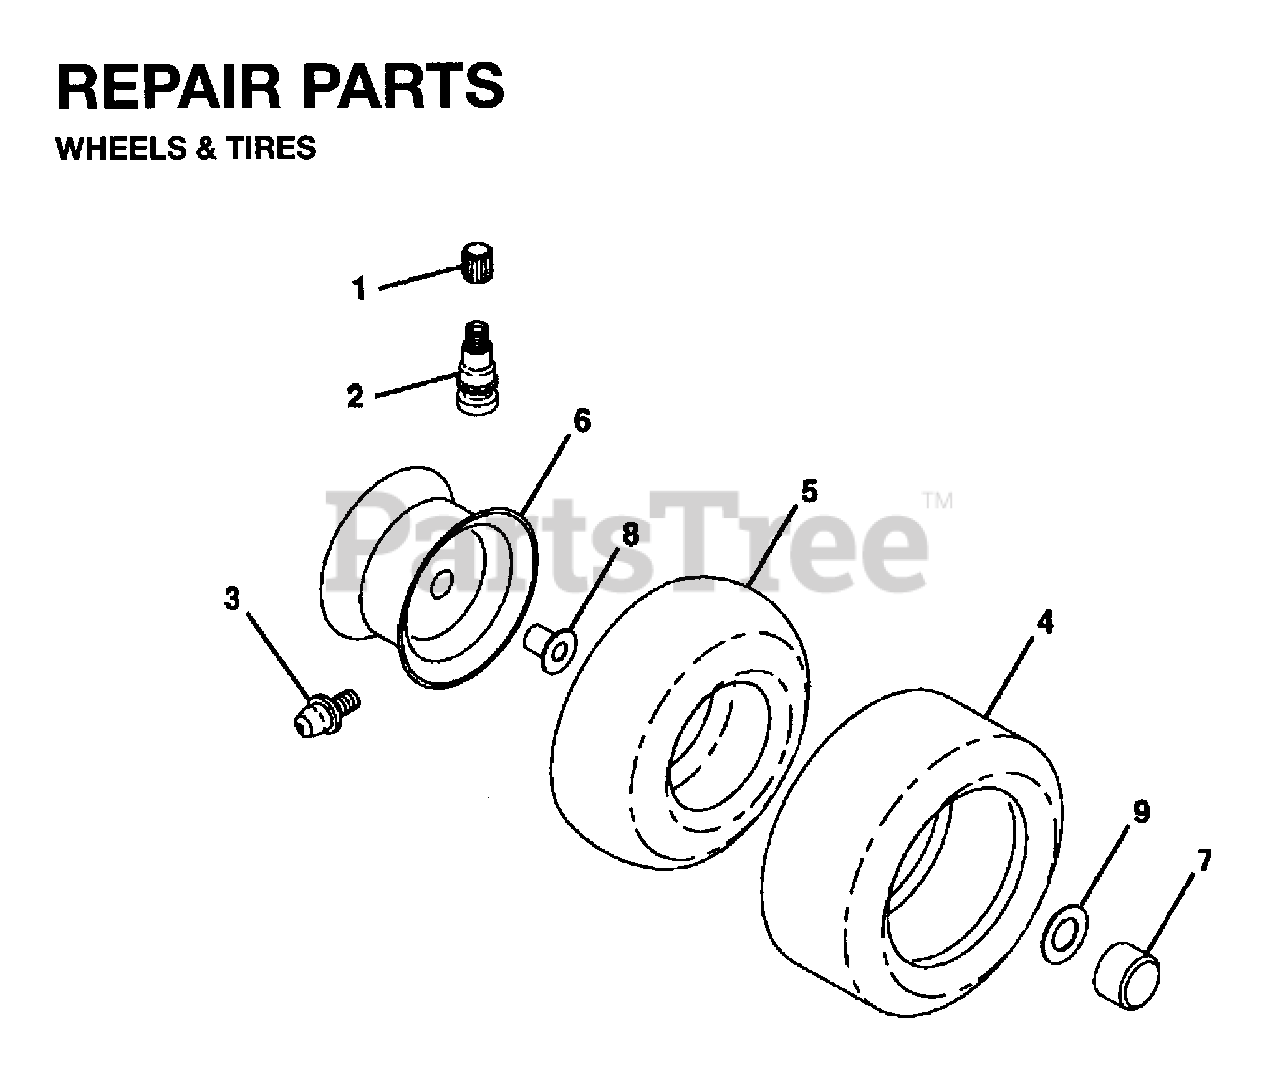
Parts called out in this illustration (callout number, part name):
1	VALVE CAP
2	VALVE STEM LT
3	FITTING LT
4	TIRE.TS 13X5-6
4	TIRE HEAVY DUTY
5	TUBE.5.3/4.5/6
5	TUBE.16X6.5/7.5-8
6	REPL BY 532 14 02-98
6	RIM REAR 8"
7	CAP-HUB FRONT LT
8	BEARING T
